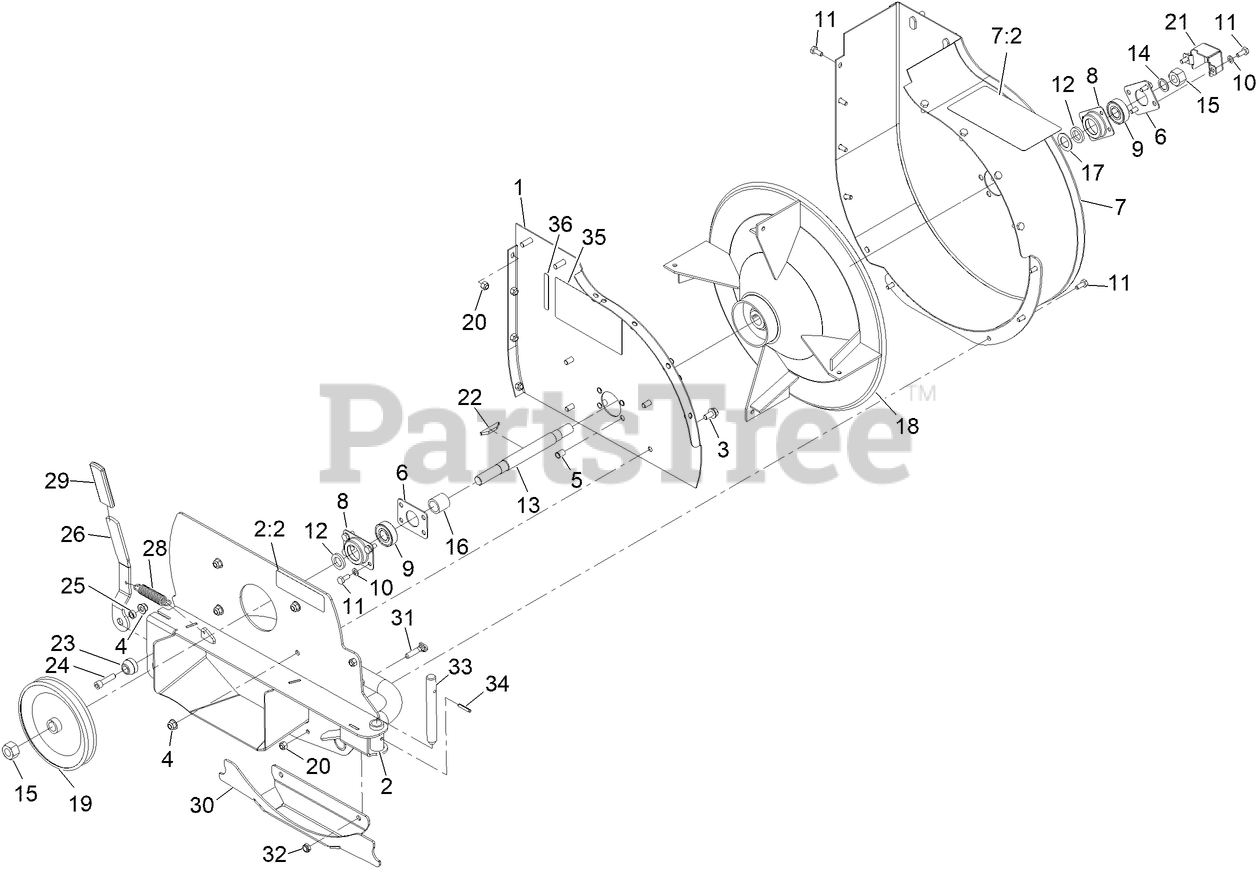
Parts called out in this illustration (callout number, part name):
1	MOUNTING PLATE ASM
2	BLOWER PIVOT ASM
2:2	DECAL-COVER, MISSING
3	SCREW-HHF
4	NUT-HF, NI
5	NUT-CLINCH
6	PLATE-COVER
7	BLOWER HOUSING OUTER ASM
7:2	DECAL-WARNING, BLOWER
8	CUP-BEARING
9	BEARING-BALL
10	WASHER-LOCK
11	SCREW-HH
12	SPACER-BEARING
13	SHAFT-BLOWER
14	WASHER-FLAT
15	NUT-HEX
17	WASHER-THRUST
18	IMPELLER ASM
19	PULLEY-TRANSAXLE
20	NUT-LOCK, NI
21	COVER-SHAFT
23	PIN-GUIDE
24	SCREW-HSH
25	SPACER-ARM, IDLER
26	HANDLE
28	SPRING-RETURN, PEDAL
30	PLATE-SKID
31	SCREW-HANDLE
32	NUT-LOCK, NI
33	PIN-BLOWER PIVOT
34	PIN-SPRING
35	DECAL-BLOWER BELT ROUTING
36	DECAL-WARNING
